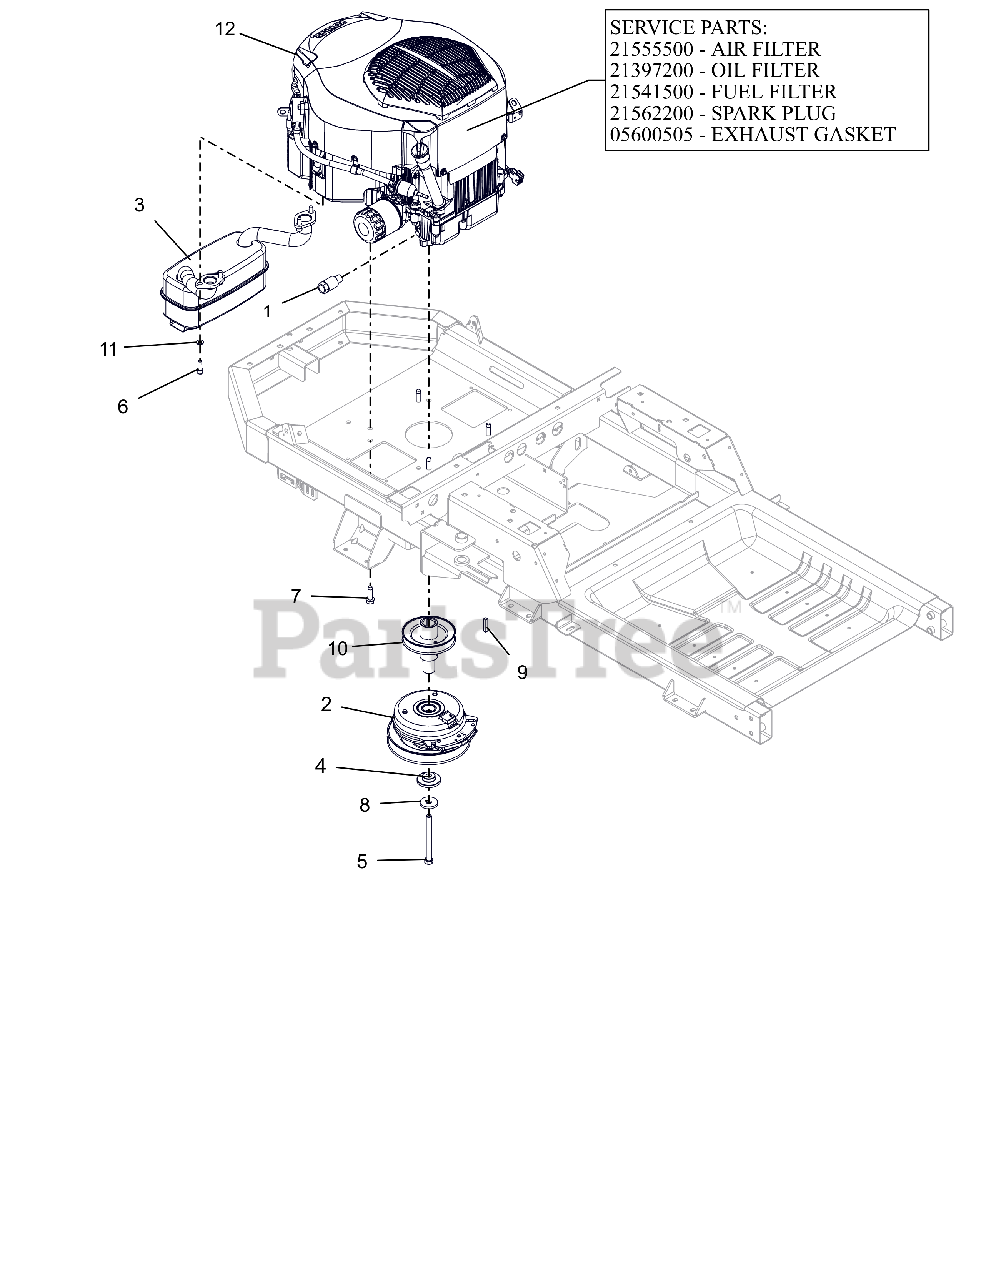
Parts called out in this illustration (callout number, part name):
1	DRAIN, OIL
2	CLUTCH,105FTLB MONOPOLE 6.83"
3	MUFFLER - KOHLER
4	BSHG-FLG .469X1.06X.574X2.0
5	BLT-HEX.438-20X4.5GR8YZ NYTORQ
6	SCR-CAP .31-18X.88 S/HD G8 ZCC
7	SCR,TAP .375-16X1.25HWH TR ZCC
8	WASHER, 7/16" SPRING DISK
9	KEY-SQ .25 X 1.25 X .25 SAE
10	WLDMT, DRIVE SHEAVE-X
11	WSHR,LK-REG .312X.078 ZCC
12	ENGINE, KOHLER 22HP TWIN
12	AIR CLEANER, KOHLER
12	FILTER, OIL - KOH CV20
12	FILTER, FUEL
12	PLUG, SPARK (RFI)
12	GASKET, MUFFLER COURAGE TWIN
